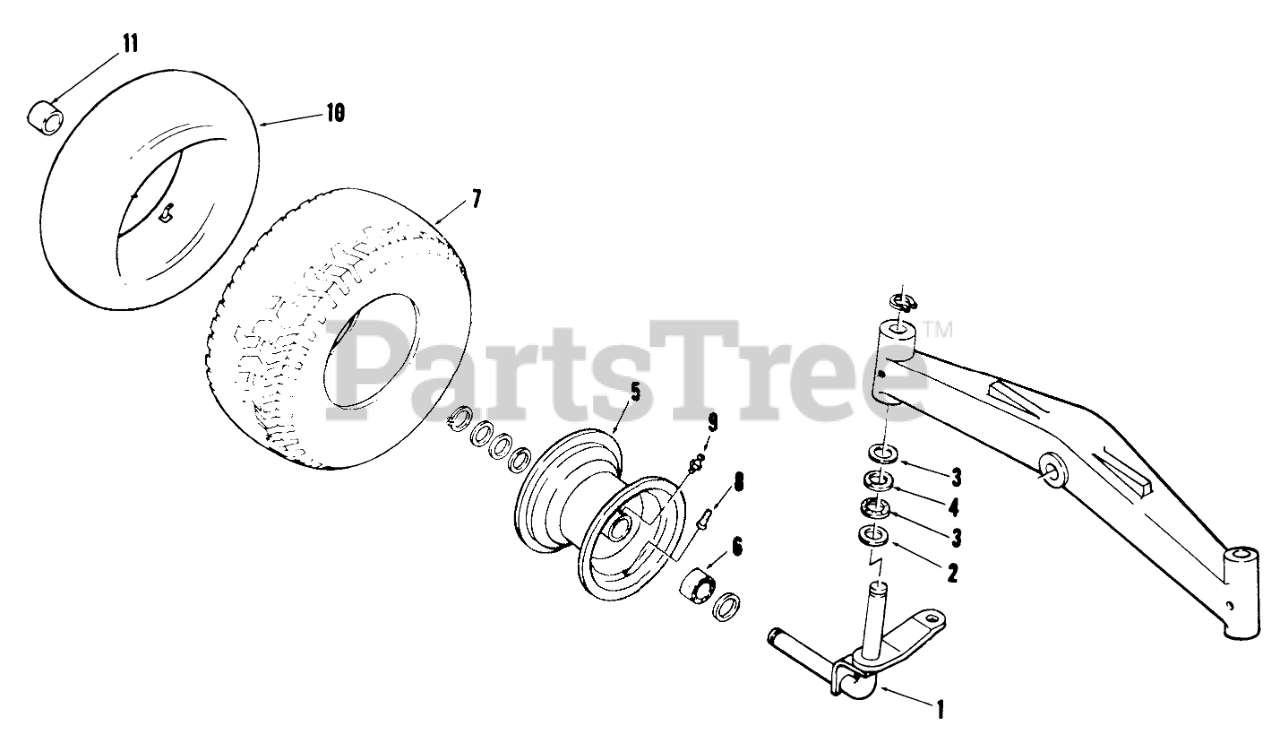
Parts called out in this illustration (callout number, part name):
1	Spindle, R.H.
1	Spindle, L.H.
2	Race Thrust
3	WASHER-SLIP
4	WASHER
5	Wheel
6	BEARING-RADIAL FLNGE
7	TIRE TURF SAVER 16X6.50-8
8	VALVE
9	Zerk
10	TUBE-INNER
11	HUBCAP
